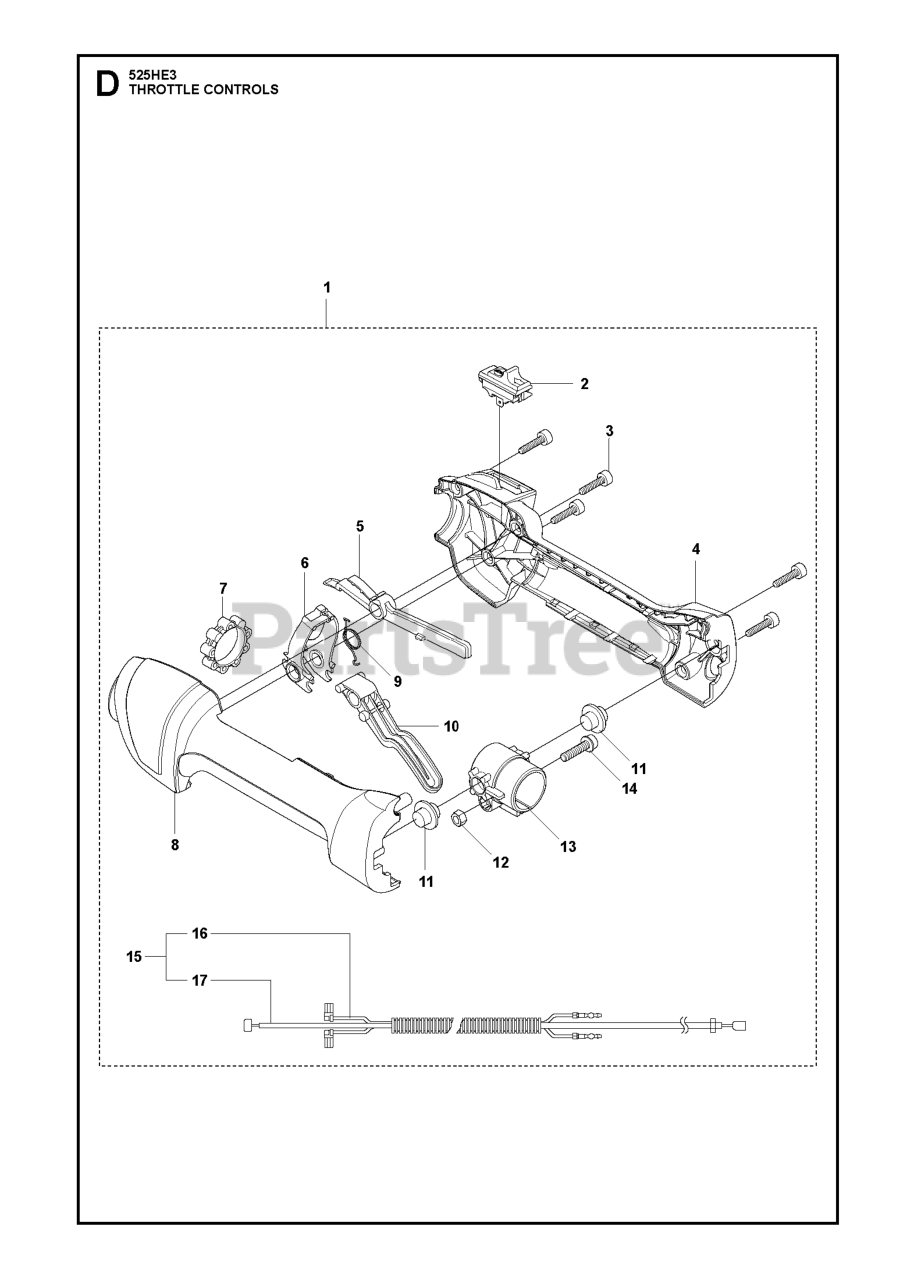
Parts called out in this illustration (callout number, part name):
1	THROTTLE CONTROL ASSY
2	STOP BUTTON
5	THROTTLE LOCK
7	VIBRATION DAMPER
9	RETURN SPRING
10	THROTTLE TRIGGER
11	VIBRATION ABSORBER
15	WIRING ASSY
16	SHORT CIRCUIT CABLE
17	THROTTLE CABLE
